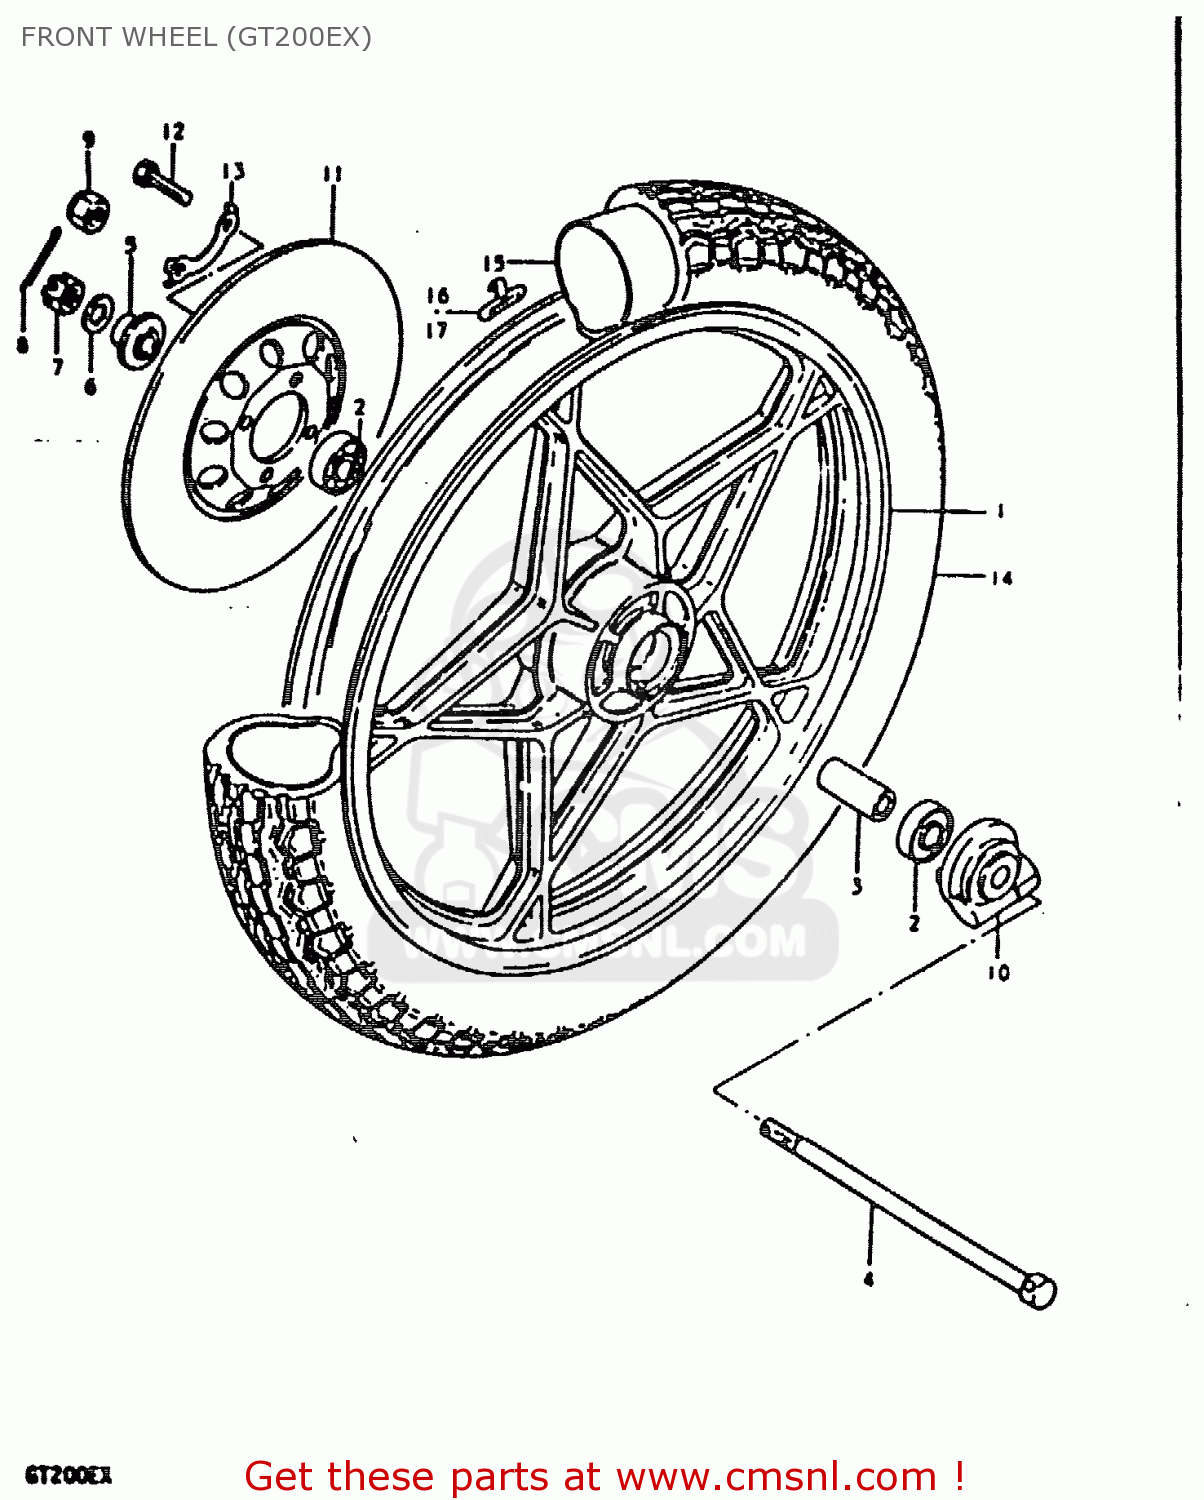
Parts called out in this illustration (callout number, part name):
1	WHEEL, FRONT
2	BEARING
3	SPACER (12.6X19X52)
4	AXLE, FRONT
5	SPACER,FR AXLE,L
6	WASHER
7	NUT 12MM
8	COTTER PIN
10	BOX ASSY,SPEEDOMETER GEAR
11	DISC,BRAKE
12	BOLT(8X25)
13	WASHER
14	TIRE,FRONT
15	TUBE,INNER
16	BALANCER,WHEEL
17	BALANCER,WHEEL
